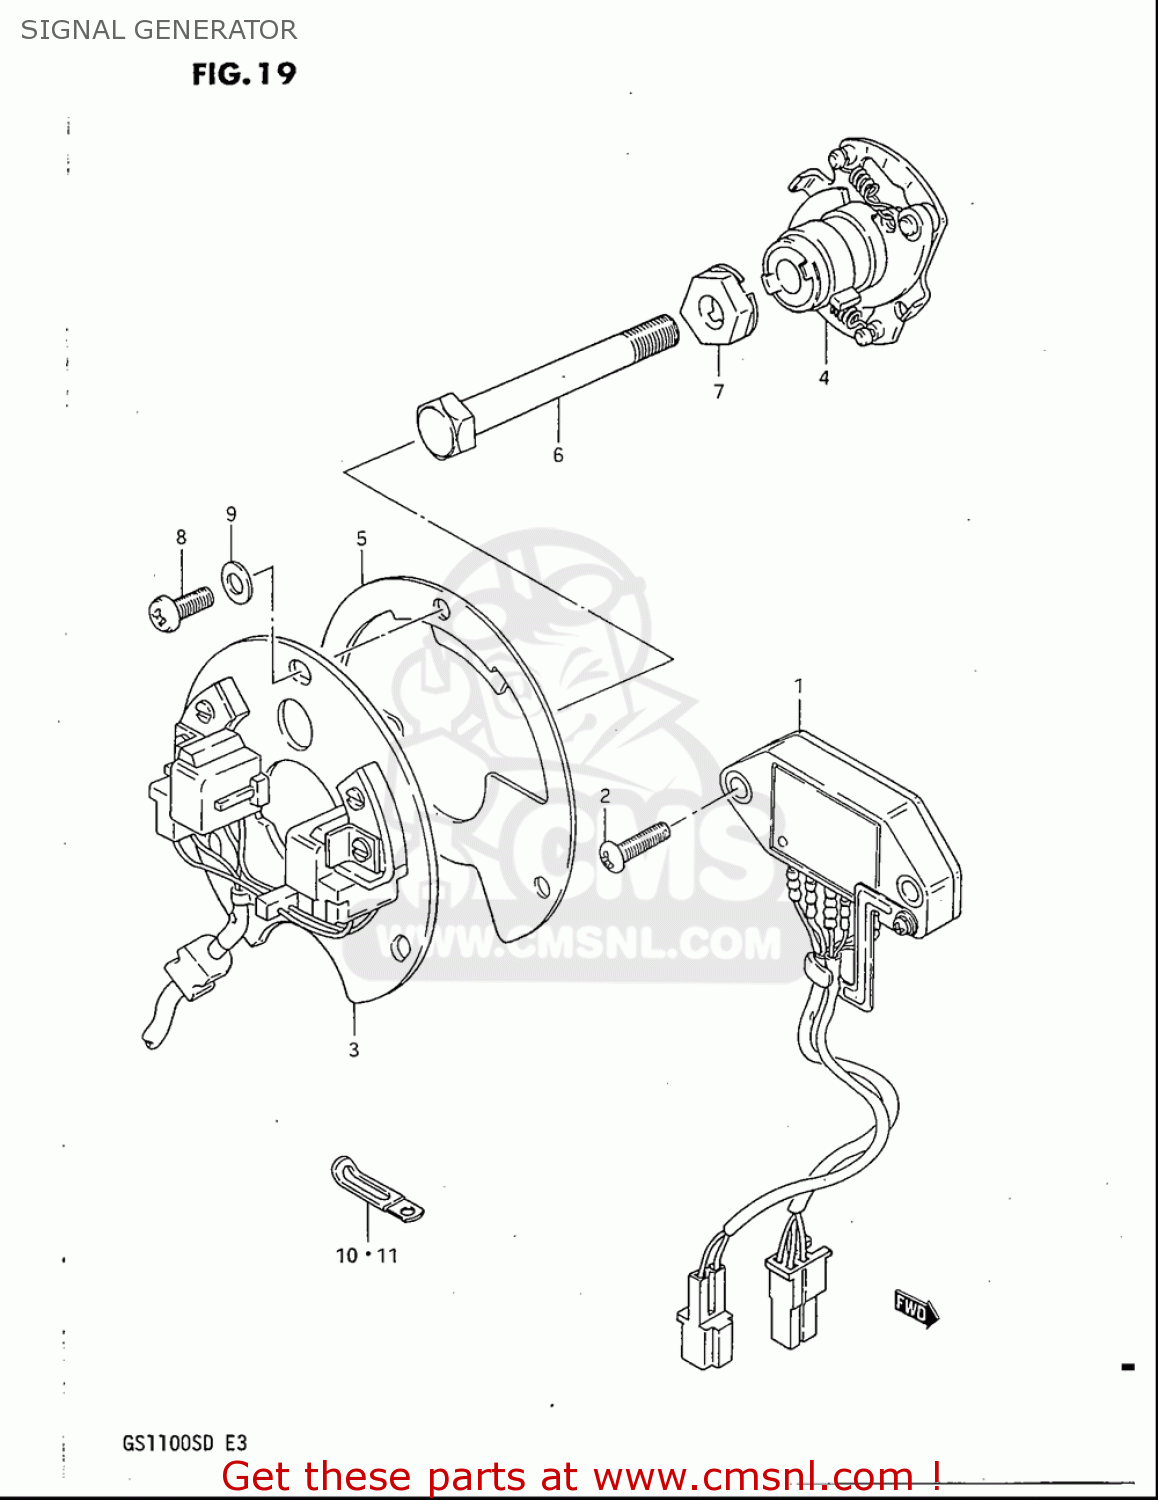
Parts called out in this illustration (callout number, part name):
1	IGNITOR UNIT
2	SCREW
3	SIGNAL GENERATOR ASSY
4	GOVERNOR ASSY
5	PLATE,TIMING
6	BOLT
7	WASHER
8	SCREW(5X12)
9	WASHER
10	CLAMP(L:65)
11	CLAMP(L:120 T:1.0)
